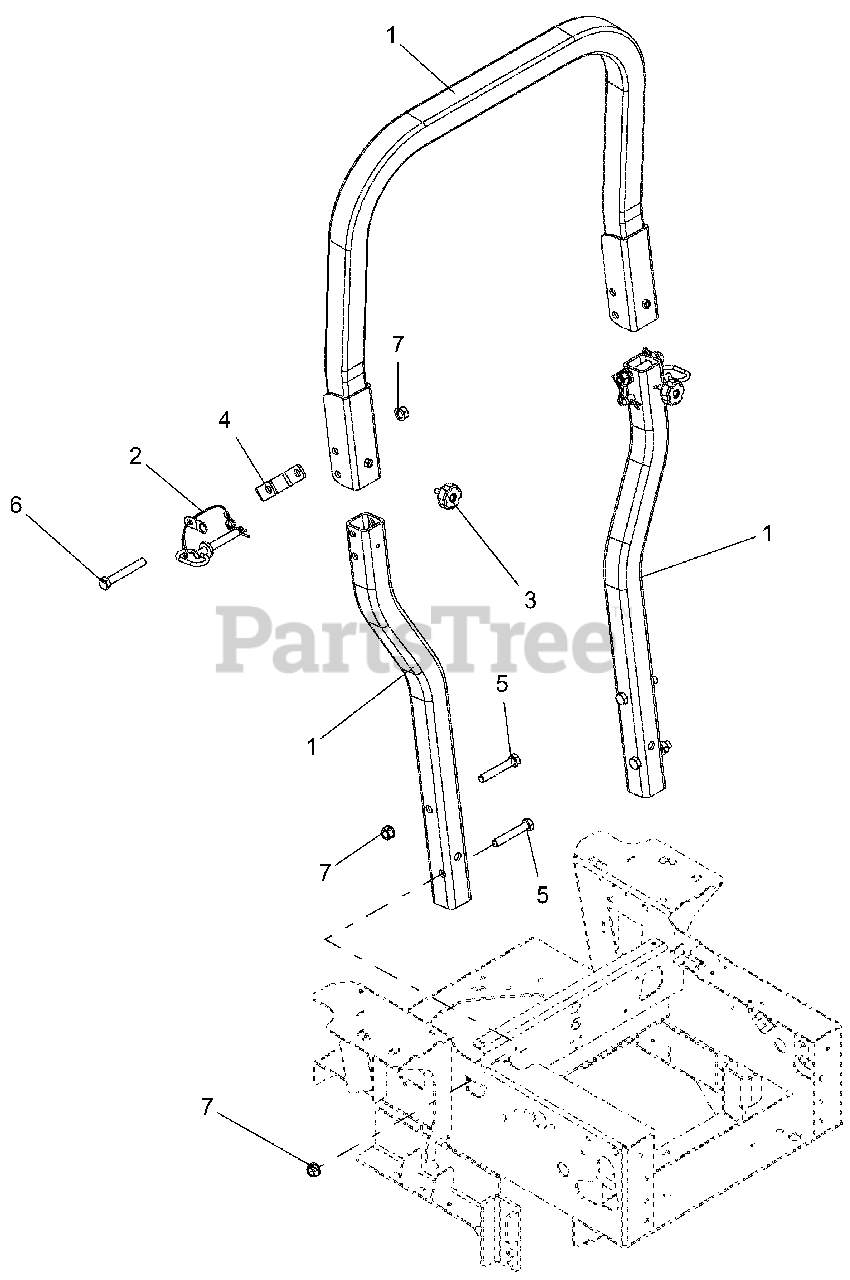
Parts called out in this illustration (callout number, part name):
1	ROPS, PT/PT100 REPLACEMENT
2	ASSY, ROPS PIN/LANYARD
3	KNOB, ROUND 5/16-18 X .750
4	BRKT, ROPS STOP, PRO-TURN YZ
5	BLT-HEX .50-13X3.00 GR5 YWZC
6	BLT-HEX .50-13X3.50 GR5 YWZC
7	NUT, LK-TOP-FLG .50-13 YWZC
